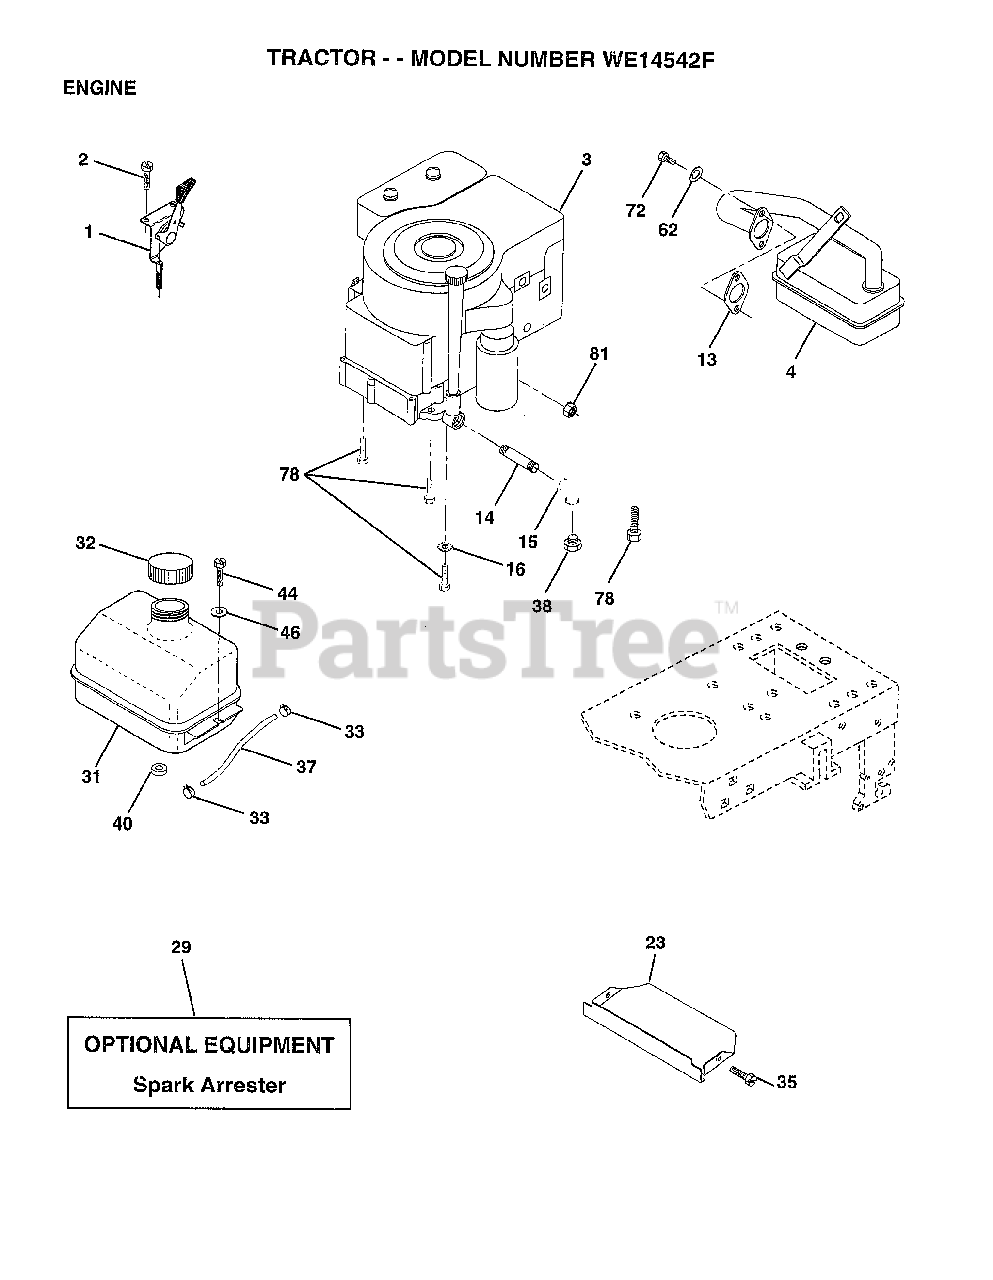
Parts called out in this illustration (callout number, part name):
1	CONTROL THROTTLE
2	SCREW LT
4	MUFFLER
13	GASKET ENG 1 313 LD TIN PLATED
14	PIPE NIPPLE
15	ELBOW
16	LOCKWASHER
23	SHIELD.BRN/DBR.GD
31	TANK.FUEL.LT.
32	CAP ASM FUEL
33	HOSE CLAMP
35	SCREW
37	LINE FUEL
44	SCREW HEX CRT
46	WASHER
62	LOCKWASHER
72	SCREW
78	SCREW
81	NUT
